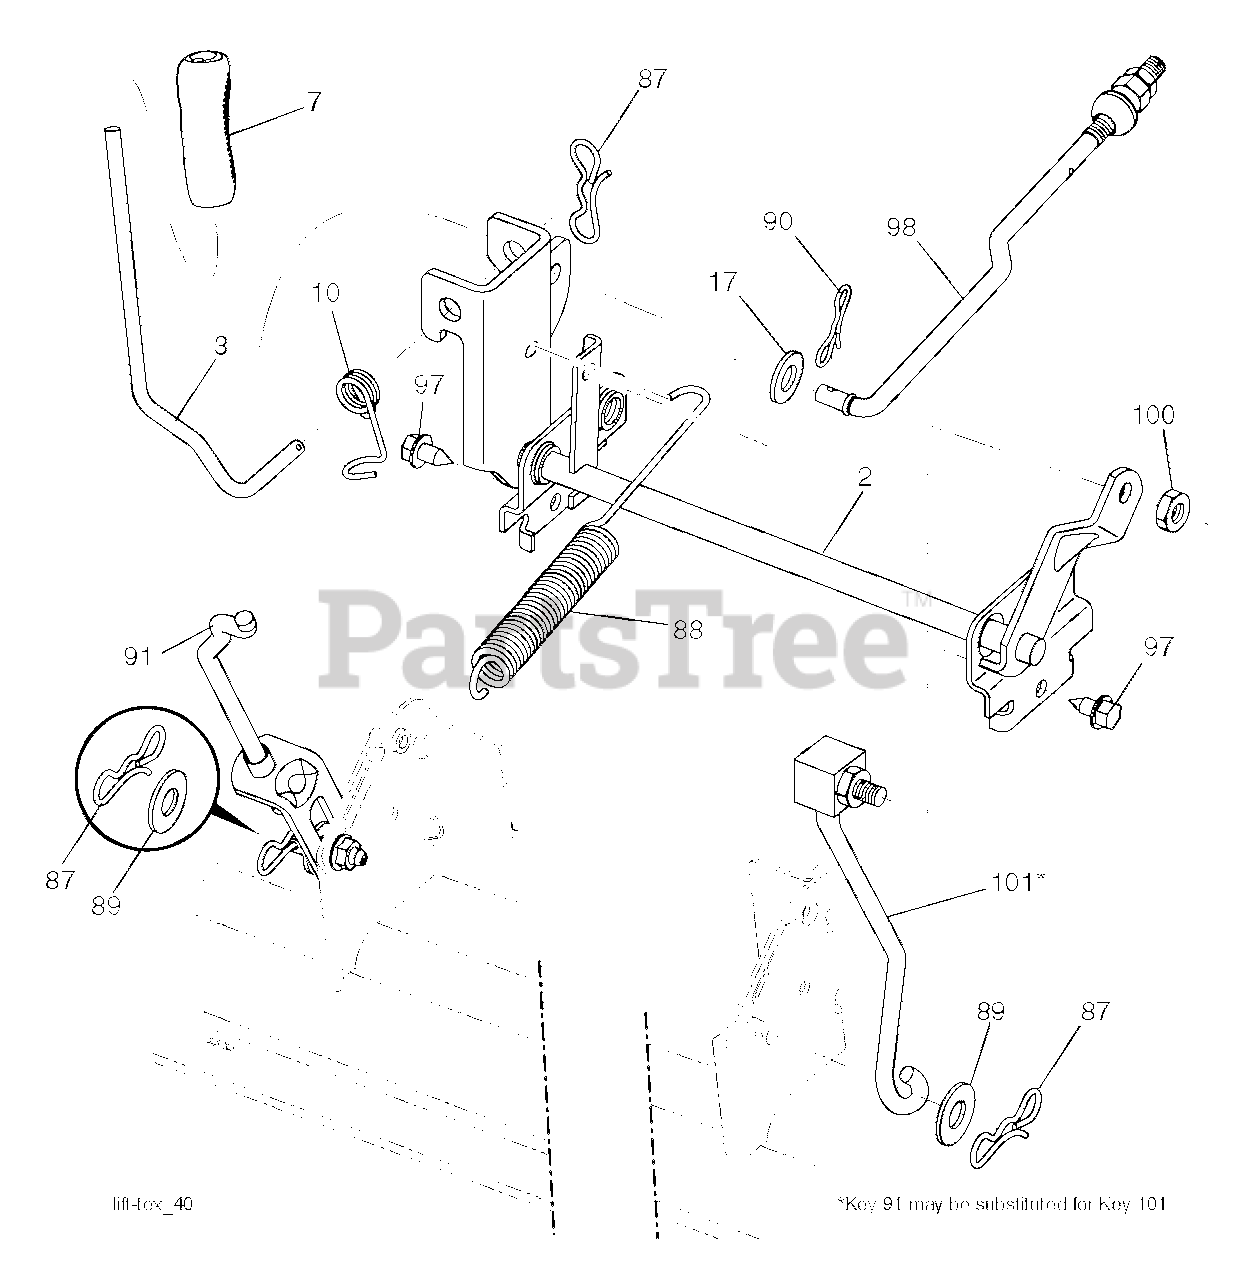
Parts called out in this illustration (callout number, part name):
2	SHAFT.ASM.CROSS.LIFT
3	LEVER.LIFT.HANDLE.LT
10	SPRING.TORSION.LIFT.HANDLE
17	WASHER
87	PIN.COTTER.7/16.BOW TI
88	SPRING.LIFT.ASSIST
89	WASHER.CLEAR.ZINC
90	PIN.COTTER.5/16.BOW TI
91	LINK.ASM.LIFT.REAR
97	SCREW, 3/8-16X3/4
98	LINK.ASM.SUSP.FRONT.MW
100	LOCKNUT
101	LINK.ASM.LIFT.FIXE.38/42/46"
